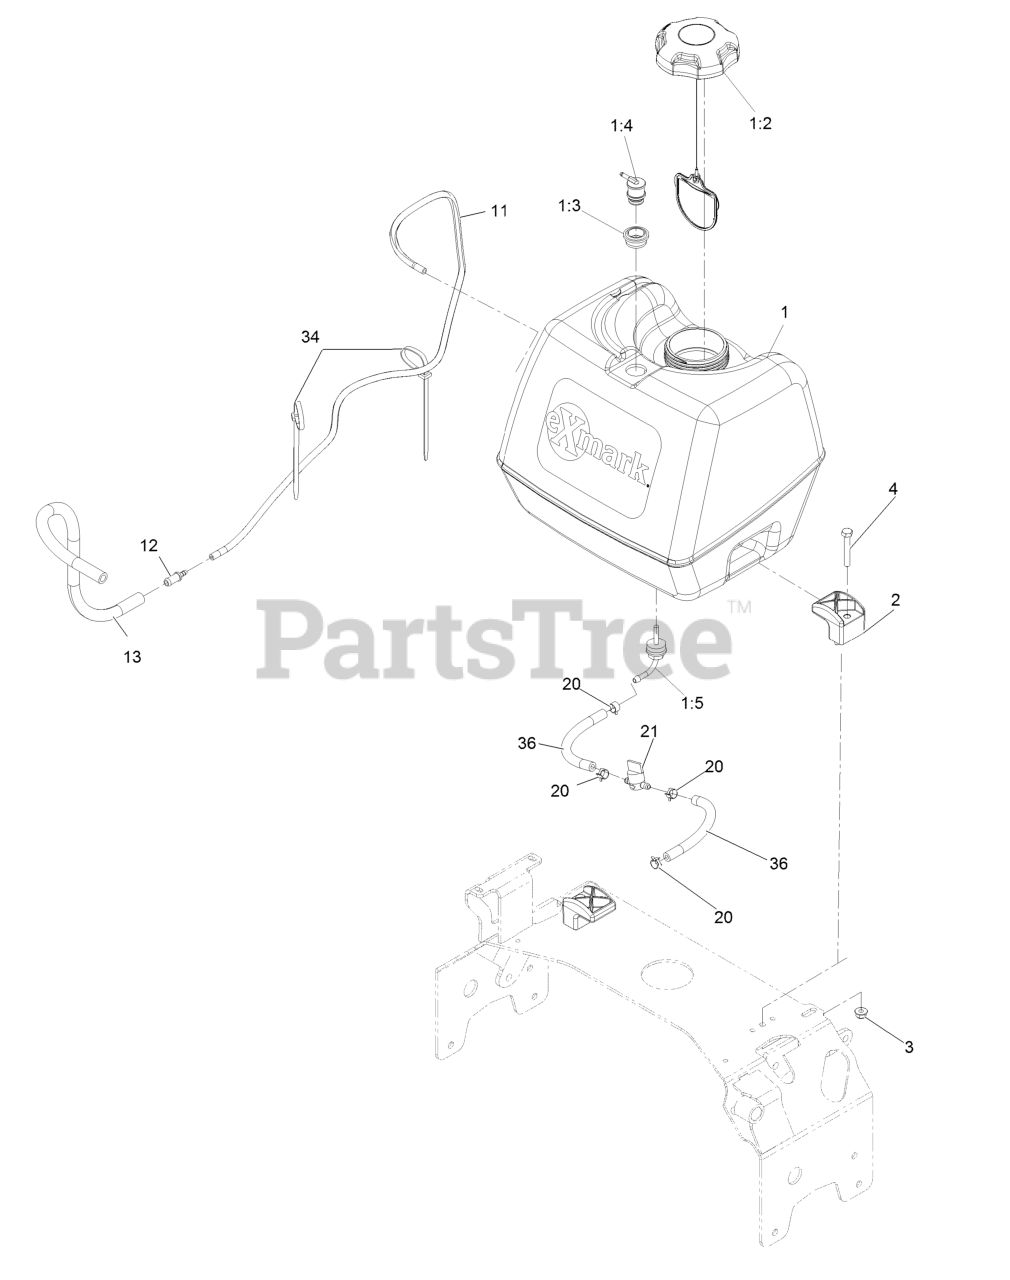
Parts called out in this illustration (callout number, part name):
1	ASM, FUEL TANK
1:3	GROMMET
1:4	VALVE-VENT, FUEL
1:5	FITTING-FUEL, BULKHEAD
3	NUT-HF, NI
4	SCREW-HH
11	HOSE, EMISSIONS
12	FITTING-STRAIGHT
13	HOSE-FUEL
20	CLAMP-HOSE
21	VALVE-FUEL
34	TIE-PLASTIC
36	HOSE-FUEL
